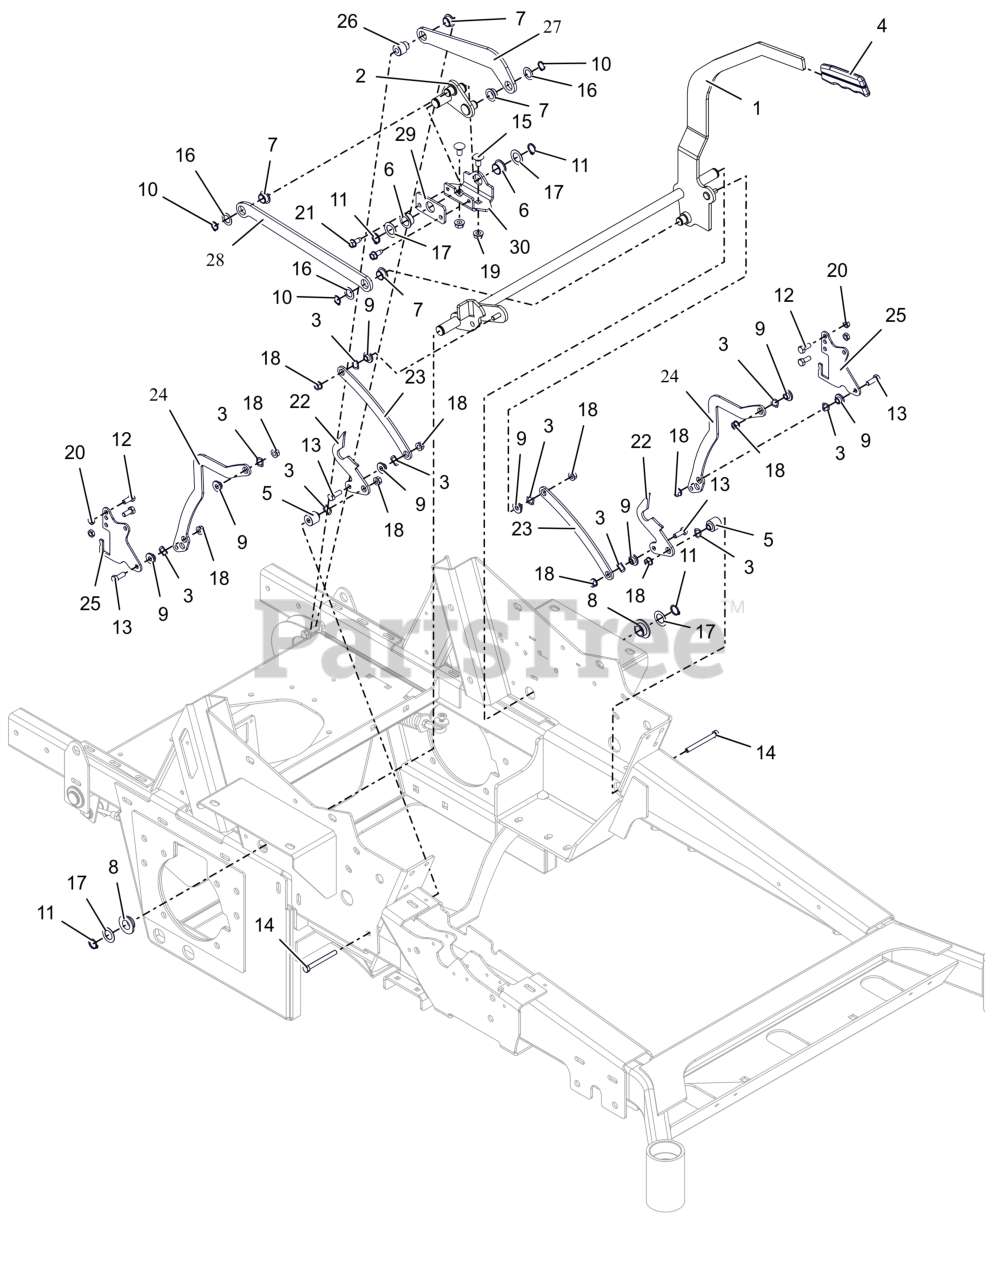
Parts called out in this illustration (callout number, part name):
1	WLDMT, PARKING BRAKE ARM (BLACK)
2	WLDMT, BRAKE ACTIVATION PIVOT
3	WAVE WASHER .531X.781X.125FH
4	GRIP, PARKING (GRAY)
5	BUSHING FLANGED - .318X.500X.972X.875
6	BSHG, FLANGE .750 X .875 X .5000 X 1.125
7	BSHG, FLANGE .625 X .750 X .375 X 1.000
8	BSHG, FLANGED .762 X 1.48 X .44 IGLIDER
9	BSHG-FLG .32X.500X.344X.880
10	RG-RTNG-EXT .625X.050
11	RG-RTNG-EXT .689X.078
12	BLT,HEX .31-18X.75 G5 ZCC
13	BLT, HEX .31-18X.875 G5 ZCC
14	BLT, HEX .31-18X3.00 G5 ZCC
15	BLT, RHSN .38-16X.750 G5 ZCC
16	WSHR-THRST .625 X 1.0 X .03
17	WSHR-HDND-THRST .758X1.23X.031
18	NUT,LK-CTR-FLG .31-18 GF ZCC
19	NUT-LK-CTR-FLG .375-16 GF ZCC
20	NUT-LK-CTR-JAM .312-18 GB ZCC
21	SCR,TAP .312-18X.75 HWH TR ZCC
22	BRKT, BRAKE - RTN (BLACK)
23	BRKT, LINK - BREAK RTN (BLACK)
24	LINK- SPEED CONTROL -HTJ (BLK)
25	BRKT, SPEED - HTG (BLACK)
27	LINK, BRAKE ACTIVATION REAR
28	LINK, BRAKE ACTIVATING FRONT
29	PLATE, BSHG MOUNTING
30	BRKT, BSHG MTG
